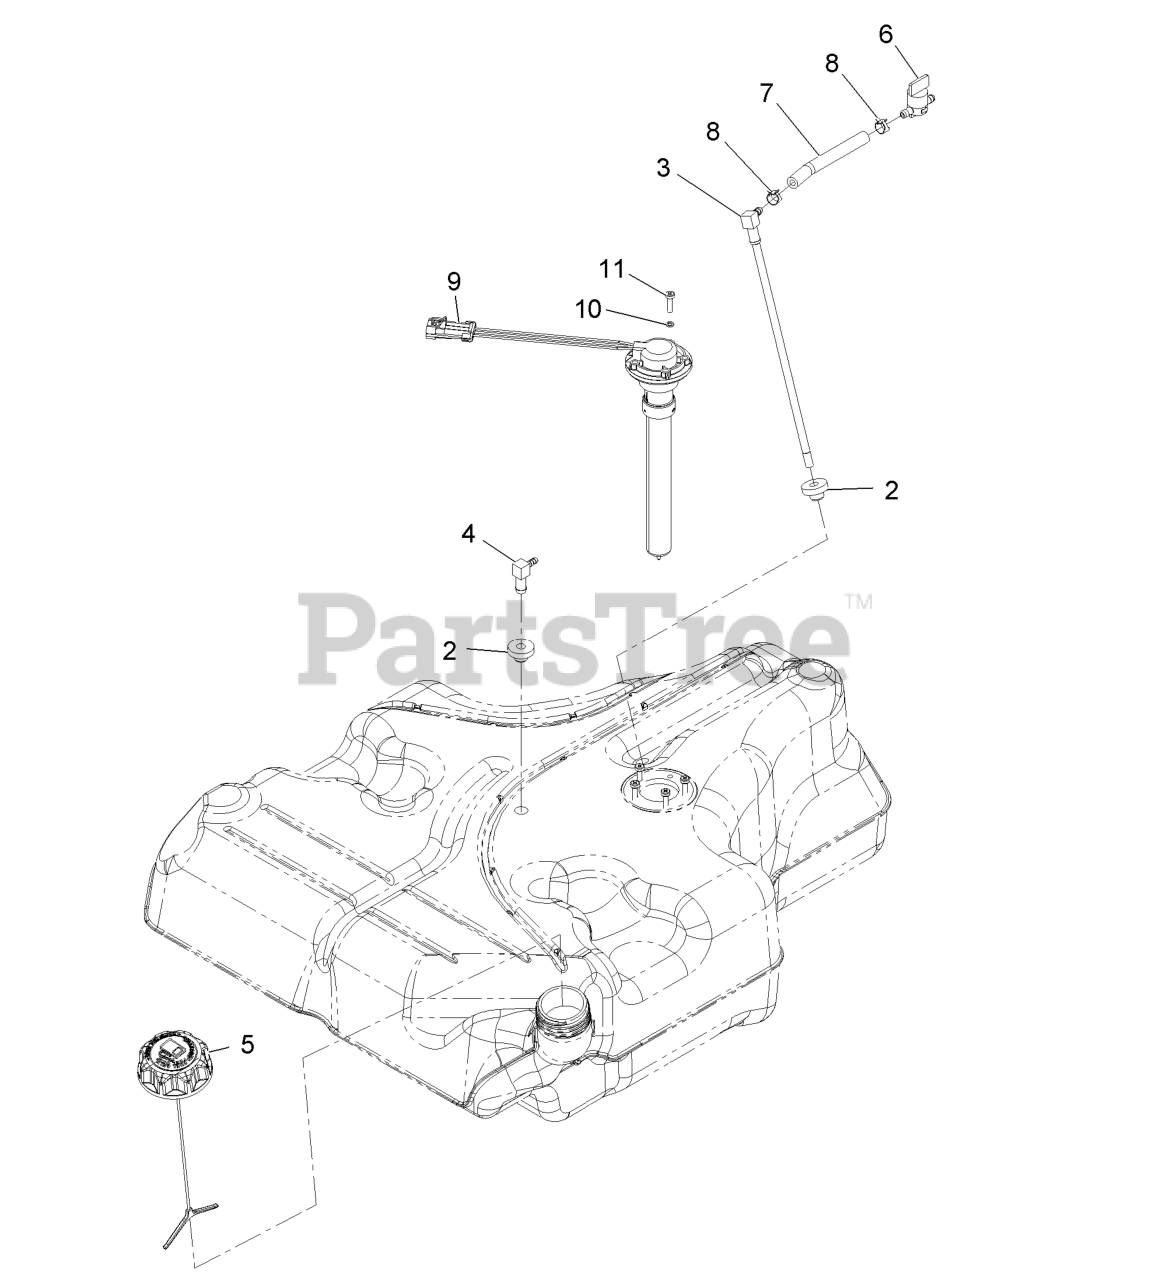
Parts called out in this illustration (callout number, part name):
2	BUSHING
3	FUEL LINE KIT (WITH GROMMET)
4	FITTING-90 ELBOW
6	VALVE-FUEL
7	HOSE-FUEL
8	CLAMP-HOSE
10	WASHER-LOCK
11	SCREW-PAN
